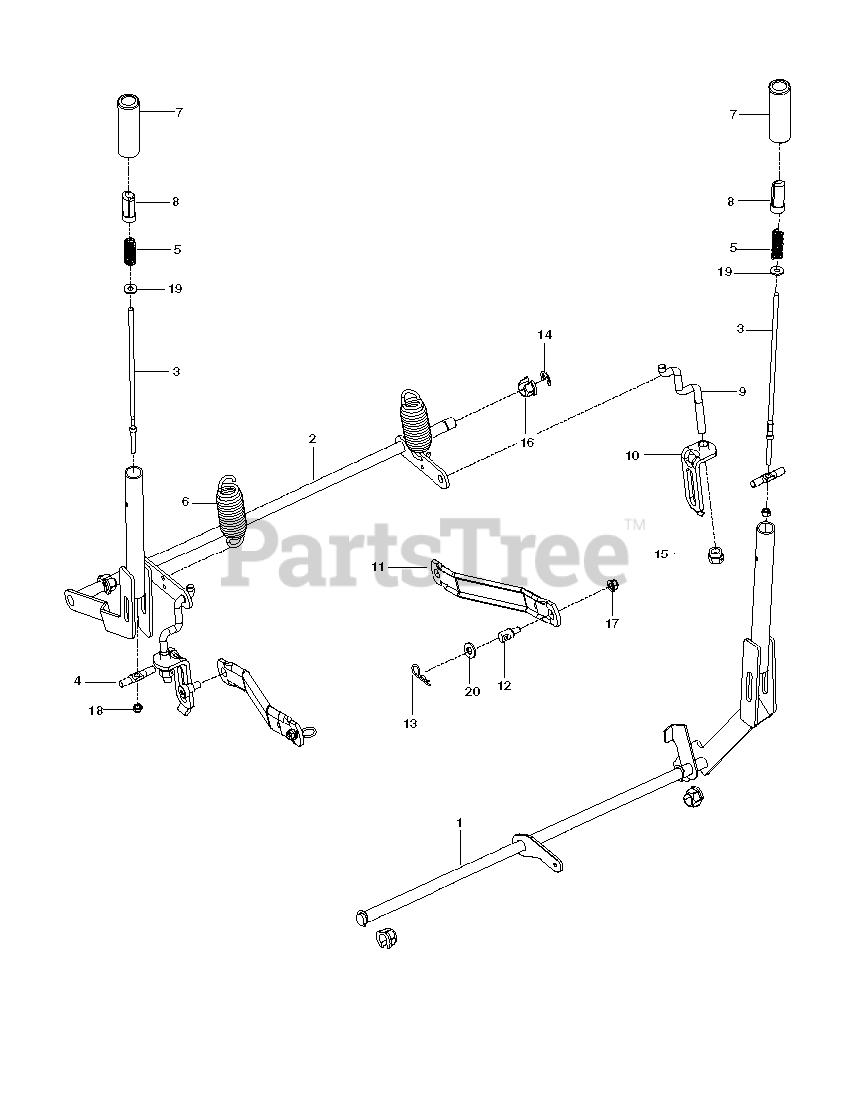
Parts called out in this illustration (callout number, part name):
1	SUBASM.SHAFT.BRAKE.WLDMNT.MED
2	SHAFT.LIFT.MED.BLACK
3	ROD, HANDLE RELEASE
4	RB ROD, LATCH RELEASE
5	SPRING, COMPRESSION
7	GRIP, HANDLE, BLACK 4"
8	BUTTON, PUSH, BLACK
9	LINK, REAR SUSPENSION
10	ASSEMBLY, BRKT LINK
11	ARM.SUSPENSION.MOWER
12	STUD.FASTNER.W/ANTI-ROTATE
13	HAIRPIN #4
14	E-RING 5/8
15	NUT, LIFT LINK 7/16-20
16	PLASTIC NUT
17	5/16-18 NYLOC FLANGE NUT
18	NUT.1/4-20.HEX.NYLOC.ZD
19	WASHER 1/4 FLAT
20	WASHER 5/8 FLAT
